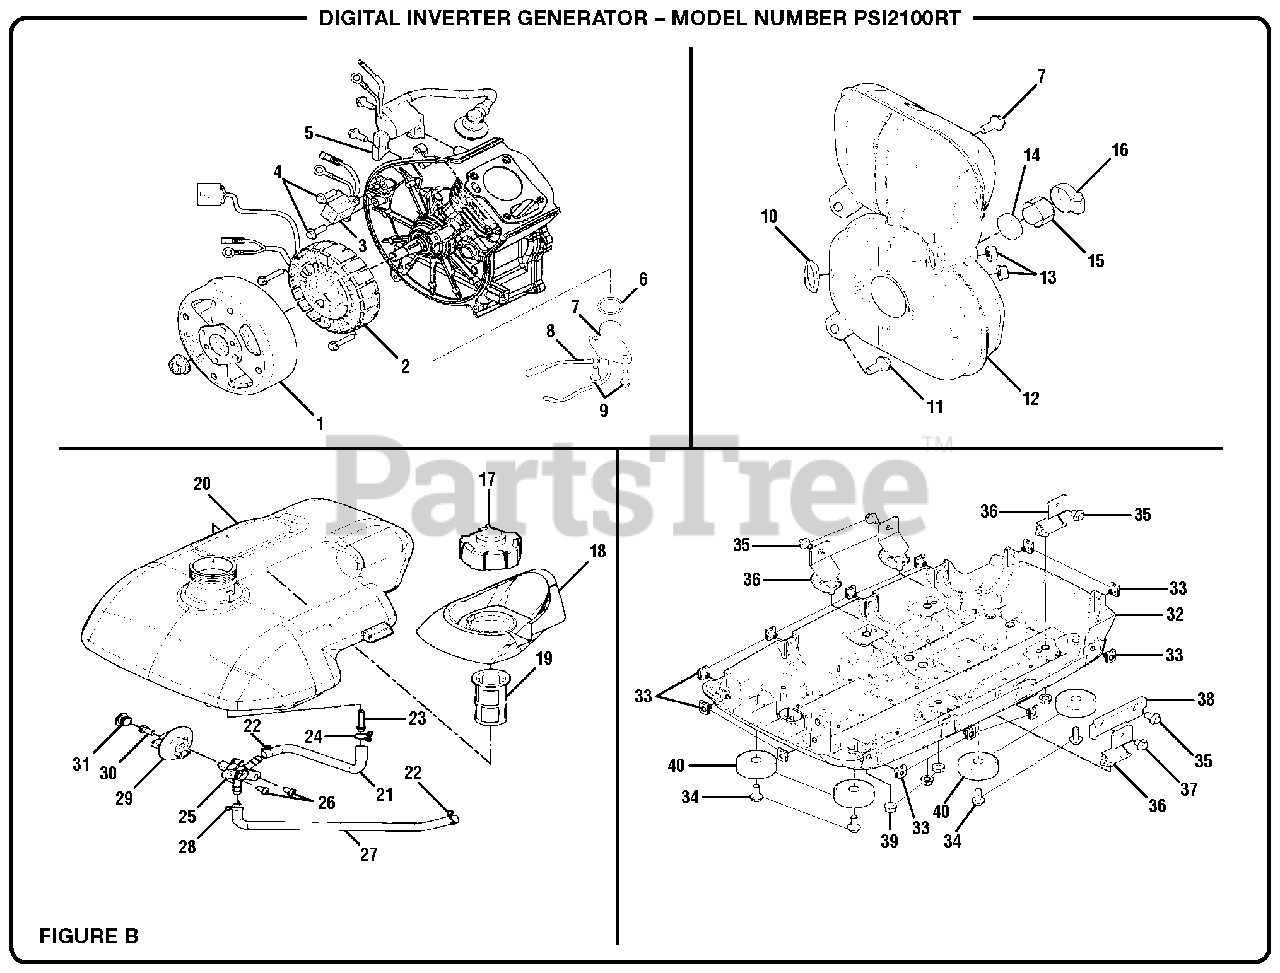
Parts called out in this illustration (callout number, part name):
1	Rotor Assembly
2	Stator Assembly
4	Bolt (M5 x 16 mm, Flange Hd.)
5	Ignition Coil Assembly
6	O-Ring (28 x 2.5)
7	Oil Level Sensor Assembly
8	Ground Wire
9	Bolt (M6 x 12 mm, Flange Hd.)
10	Exhaust Pipe Gasket
11	Bolt (M6 x 12 mm, Flange Hd.)
12	Muffler Assembly
13	Hex Nut (M6)
14	Spark Arrestor
15	Spark Arrestor Bracket
16	Adjustable Clamp
17	Fuel Tank Cap
18	Overspill Guard
19	Fuel Filling Strainer
20	Fuel Tank
22	Clip Q671B (8.5 mm)
23	Inline Fuel Filter
25	Fuel Switch Assembly
26	Screw (ST4.2 x 13 mm)
29	Main Switch Knob
30	Screw w/Washer (ST4.2 x 12 mm, Pan Hd.)
33	U-Clip w/ Nut (M5)
34	Bolt (M6 x 16 mm, Flange Hd.)
35	Bolt (M6 x 12 mm, Flange Hd.)
37	Bolt (M6 x 8 mm, Flange Hd.)
38	Bracket (Engine)
39	Flange Nut (M6)
